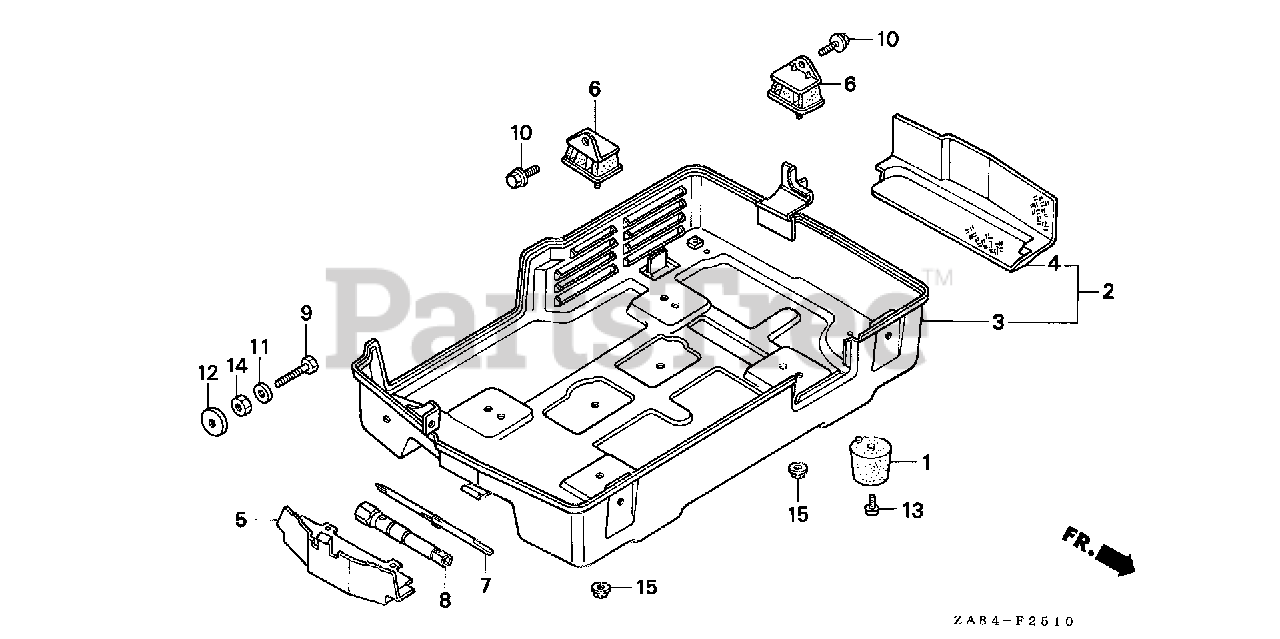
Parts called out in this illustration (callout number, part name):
1	RUBBER (LOWER)
2	COVER ASSY. (LOWER)
3	COVER (LOWER)
4	WOOL, COVER GLASS (LOWER)
5	COVER, TOOL
6	RUBBER, SETTING
8	WRENCH, BOX (P19X10) (NOT AVAILABLE)
9	BOLT, HEX. (6X18)
10	BOLT, FLANGE (6X12) (CT200)
11	WASHER, SPRING (6MM)
12	NUT, SPECIAL (6MM)
13	SCREW, PAN (6X10)
14	NUT, HEX. (6MM)
15	NUT, FLANGE (6MM)
